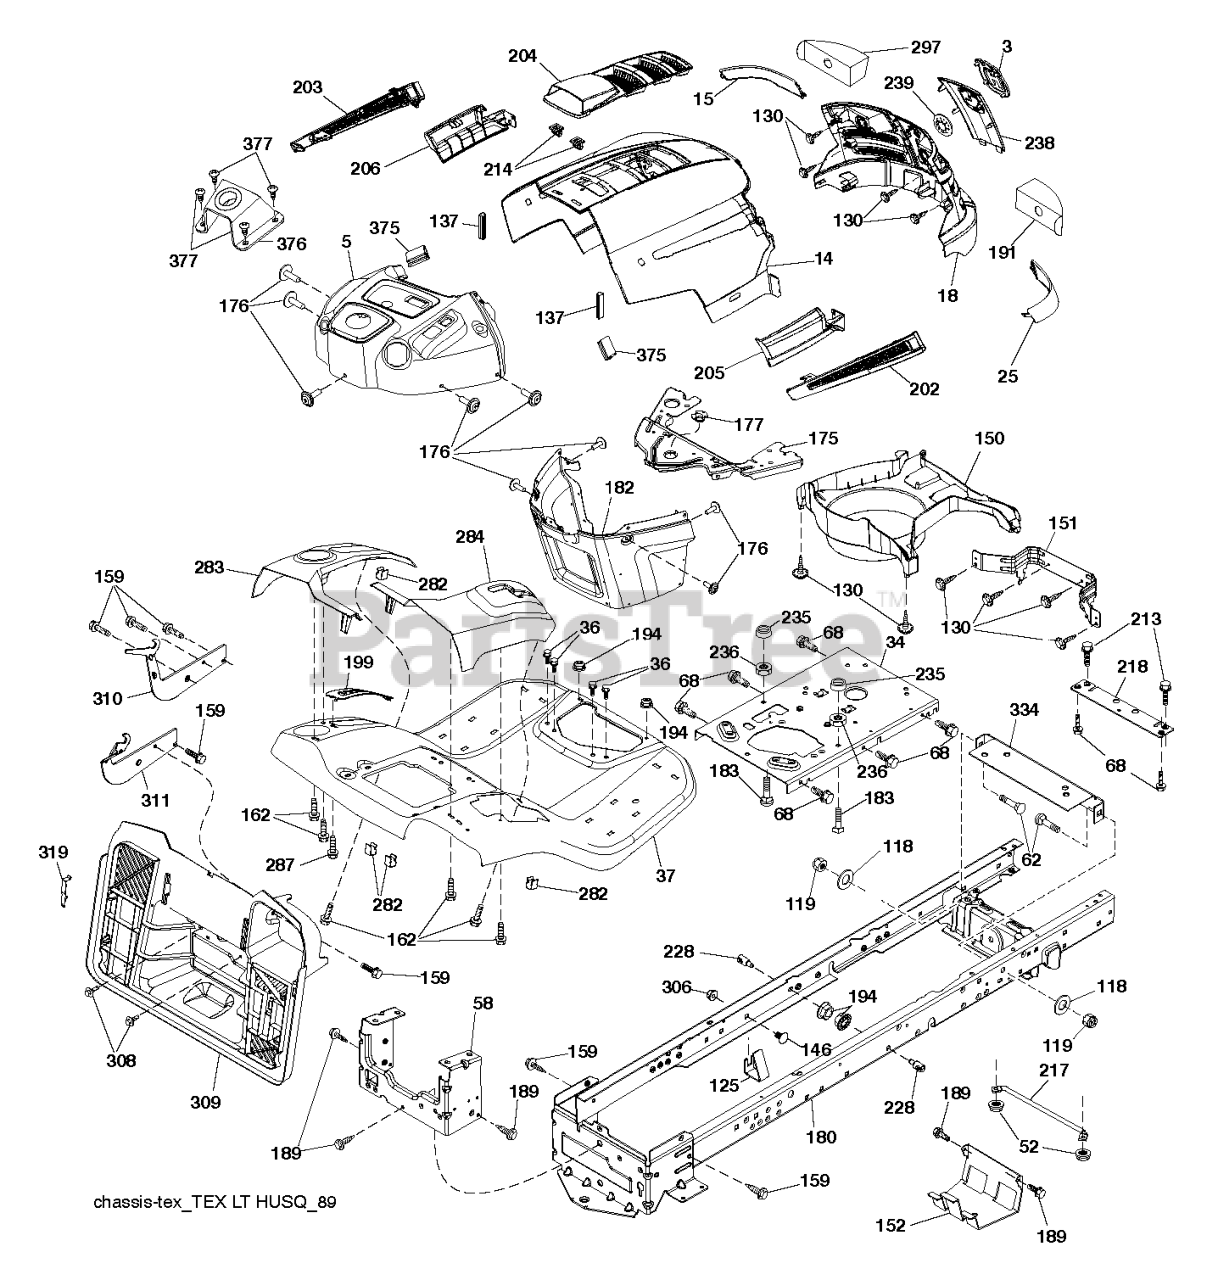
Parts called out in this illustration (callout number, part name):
3	LOGO.HUSQ.GT.LT.CROWN.H
5	DASH.UP.HUS.CABLE.CLUTCH
14	HOOD.HUSQVARNA.LT.ORANGE
15	LENS.HUSQVARNA LT.RH
18	ASM.GRILLE HUSQVARNA.LT.498
25	LENS.HUSQVARNA LT.RH
36	SCREW 5/16"
37	FENDER.TEX.SRD.CRD.BASE
58	DRAWBAR UPPER 2PC SMALL FENDER
118	WASHER
125	CLIP.FUEL.LINE
137	BUMPER DASH
146	BOLT.RDHD.SHT.SQNK.3/8-16X5/8
151	BRACKET PIVOT
152	SHIELD.BROWNING.W/TEX
159	SCREW, 3/8-16X3/4
175	CROSSMEMBER
176	SCREW.#10-24X5/8.RN.QU
177	BUSHING STEERING
180	CHASSIS.WLDMNT.14GA.2PC.18".TI
182	DASH.LOWER.PREDATOR LT
189	SCREW
191	INSERT.REFLECTIVE.RH.
199	PLATE DECK LIFT
202	VENT.SIDE.HUSQVARNA.LT.RT
203	VENT.SIDE.HUSQVARNA.LT.LFT
204	SUBASM.TOP.VENT.HUSQ.LT
205	SKIRT.SIDE.HUSQVARNA.LT.RT
206	SKIRT.SIDE.HUSQVARNA.LT.LEFT
213	SCREW HEXAGON HEAD SCREW 5/16-
214	CLIP.RETAINER.TINNER.
217	ROD.PIVOT.HOOD
218	X-PIECE.HOOD.STOP.NON/
228	STUD.W/"D"ANTI-ROTATION
236	NUT.CENTERLOCK.5/16-
238	TRIM.HUSQ LT.668
282	CLIP.RETAINER.CONSOLE.LT.HUSQ
283	CONSL.DECKLIFT.LH.SRD.TEX.CRD
284	CONSL.SHFT.PEDAL.RH.SRD.TEXCRD
287	SCREW 1/4X20
297	INSERT REFLECTIVE
306	NUT LOCK FLG 3/8-16 UNC
308	BOLT.5/16-18UNCX3/4 W/SEMS.BLK
309	BACKPLATE.BAGGER.V2.SRD
310	BRACKET BRACKET.LH REAR BAG HA
311	BRACKET BRACKET.RH REAR BAG HA
319	BRACKET.ACTUATOR.BAGGER.SRD
334	BRACKET.ENGINE
375	BUMPER CLIP-ON. DASH 1"
376	MOUNT.ASM.HUSLT.UPPER.STRNG
377	SCREW 10 X 1/2 ZN PL PHIL PAN
